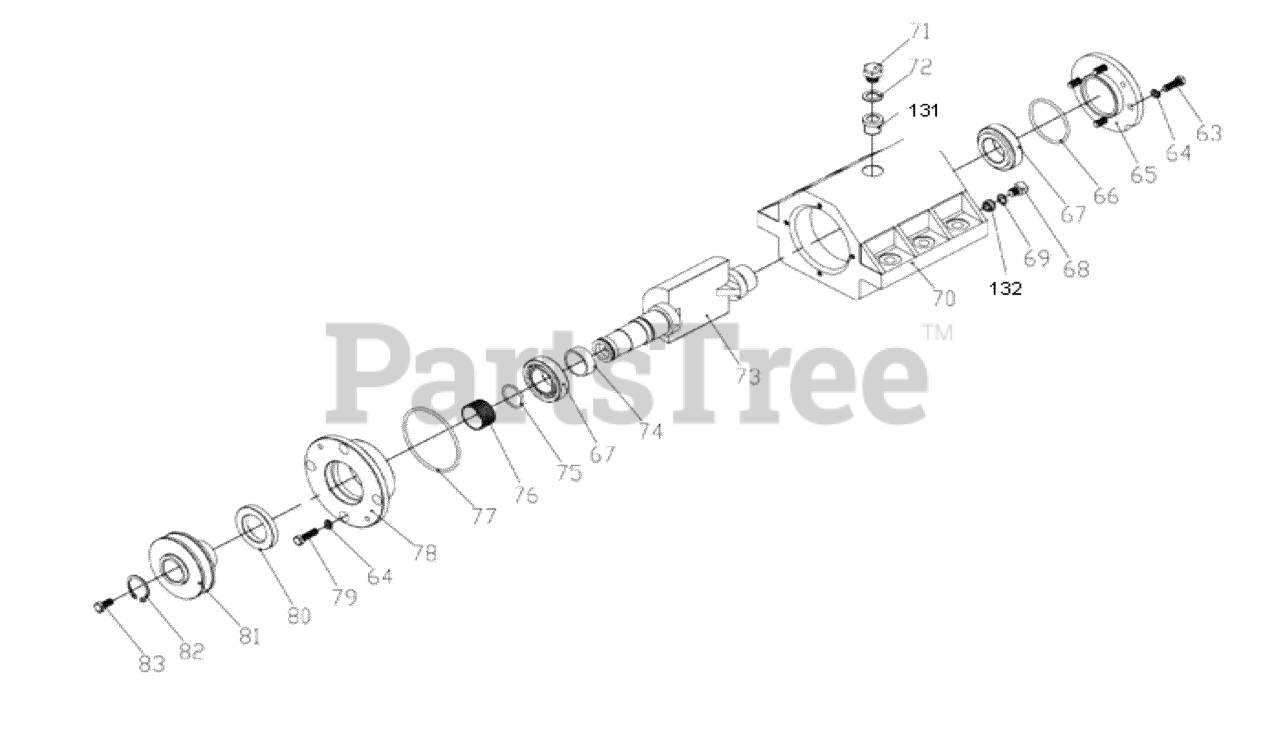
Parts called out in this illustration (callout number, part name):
63	BOLT, Hex Head, M8 x 30
64	WASHER, Spring, 8
65	COVER, Eccentric Box
66	O-RING
67	BEARING, Single Row Roller
68	PLUG, Socket Head Hex
69	GASKET, 10
70	ECCENTRIC BOX
71	PLUG, Hex Head
72	GASKET, 14
73	ECCENTRIC SHAFT
74	BEARING, Needle Roller, Inner Ring
75	O-RING
76	BUSHING
77	O-RING
78	COVER, Eccentric Box
79	BOLT, Hex Head, M8 x 30
80	OIL SEAL
81	PULLEY, Eccentric Box
82	CIRCLIP
83	BOLT, Venting
131	THREAD BUSHING, B
132	THREAD BUSHING, A
